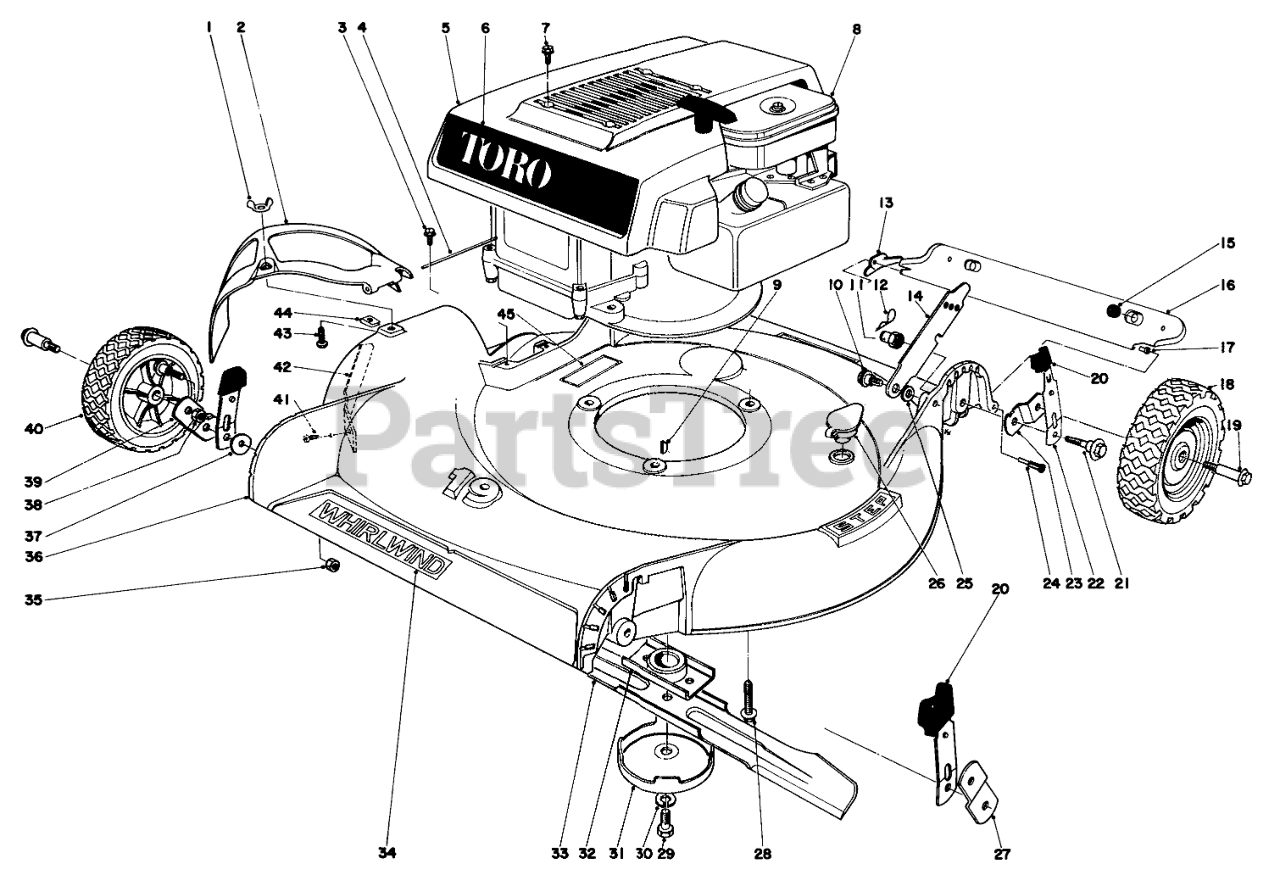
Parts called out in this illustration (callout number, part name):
1	NUT-WING SPECL
2	Deflector
3	SCREW
4	HINGE PIN
5	Shroud
6	Decal Whirlwind
7	Capscrew
8	Engine (Model 16073)
9	KEY-WOODRUFF
10	SCREW-SHOULDER
11	HANDLE PIVOT NUT
12	PIN-COTTER, HAIR
13	Restraint R.H.
14	Latch
15	SKID BUTTON
16	Safety Shield (Incl. Ref. #15 & 17) (Model 16073)
17	SAFTEY SHIELD BUSHING
18	Wheel Assembly
20	KNOB-ARM
21	PIVOT SCREW
22	SPRING ARM ASM
23	PIVOT ARM PLATED
24	SAFTEY SHIELD SCREW
25	SPACER
26	Plug Washout
27	PIVOT ARM C PLTD
28	SCREW-HWHTF
29	SPECIAL SCREW
30	WASHER-LOCK
31	Anti Scalp Cup
32	Blade Retailer
33	Blade
34	Decal Toro
35	Nut
36	Housing (Model 16073)
37	Washer
38	Nut
39	PIVOT ARM D PLTD
40	Wheel Assembly
41	SCREW-HWH
42	Bar Safety
45	Decal
